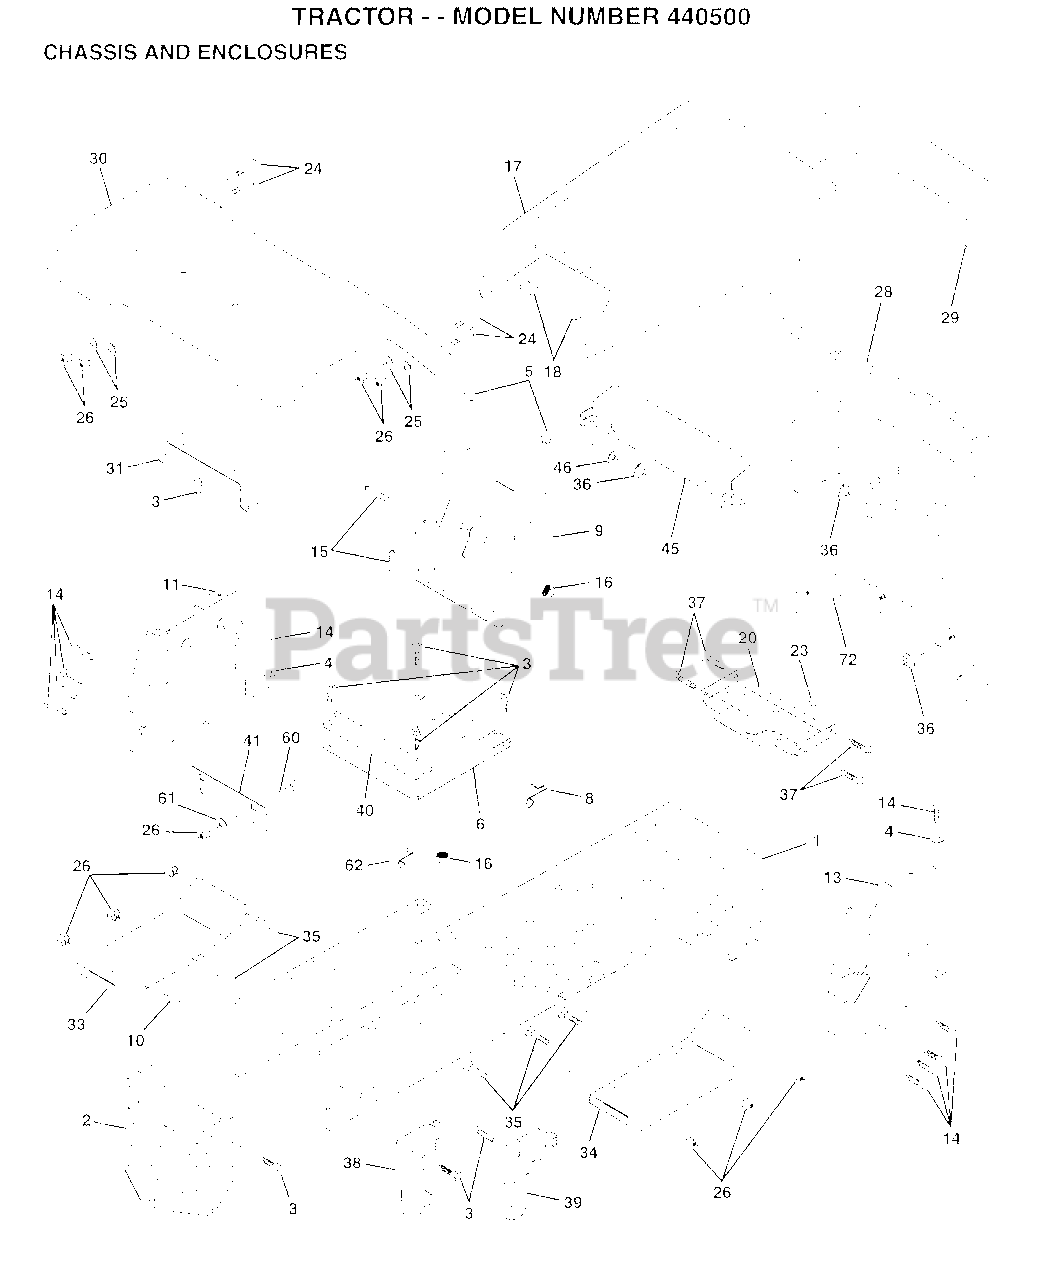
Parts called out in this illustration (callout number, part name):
1	CHASSIS.WLD.11GA
3	SCREW
4	WASHER
8	"CLIP,INSULATOR"
11	PANEL.DASH.LH.
12	CLIP.TINNERMAN
13	PANEL.DASH.RH
14	SCREW LT
20	PLATE.MTG.BTRY.TK
24	BOLT
25	WASHER
26	NUT
29	LENS GRILLE
31	BRACKET SUPT FEND
33	FOOTREST.LH.LT/GT
34	FOOTREST.RH.LT/GT
35	BOLT
37	SCREW LT
38	BRACKET ASM LH
40	SPACER FENDER LT
41	PLATE EXTEN FEND
48	RIVET.PUSH.PLATE
49	SCREW HEX CRT
50	BRACE SUPT DASH
51	NUT
52	WASHER
53	BRACKET.GRILLE.LH
55	BRACKET.GRILLE.RH
58	DUCT.AIR.B&S.18HP
60	BOLT
61	WASHER
68	NUT
